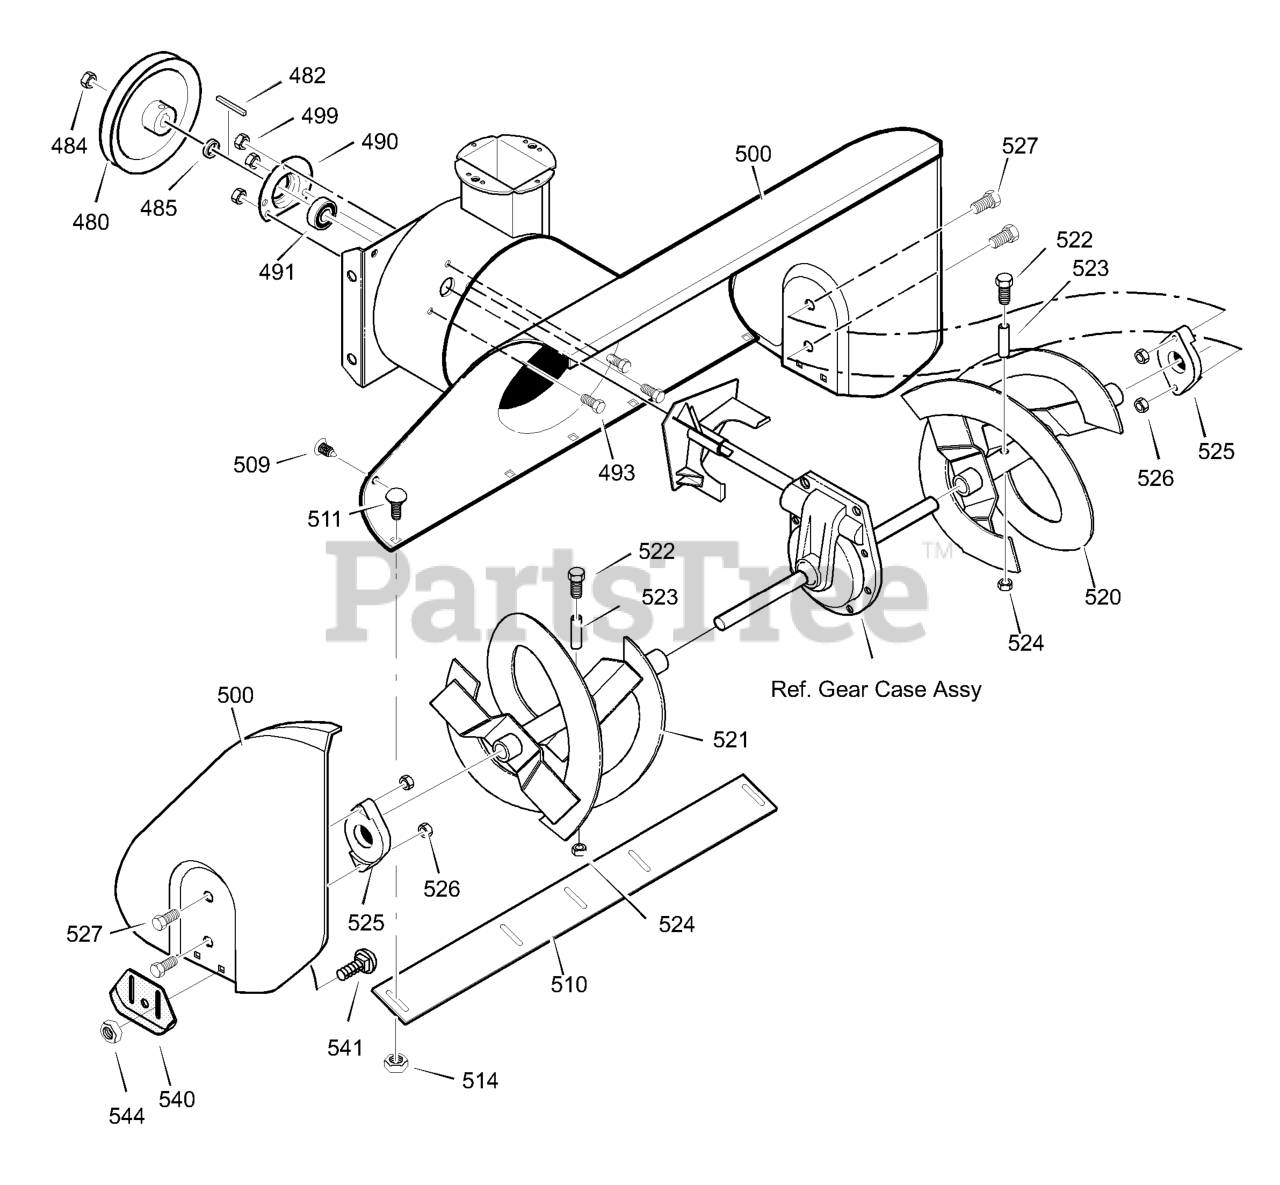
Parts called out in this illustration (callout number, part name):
480	PULLEY, 4L 8.40 OD
482	KEY, SQUARE 3/16 X 3/4
484	NUT, 1/2-20
485	SPACER, FRICTION PULLEY
490	RETAINER, BALL BRNG
491	BEARING, BALL
493	BOLT, HEX 5/16-18X .50
499	NUT, 5/16-18 HEXWDFLLK
500	HOUSING, ASSY
509	PLUG, CHRISTMAS
510	BLADE, SCRAPER
511	BOLT, 5/16-18X.75
514	NUT, 5/16-18
520	AUGER, ASSY, LH
521	AUGER, ASSY, RH
522	SCREW, 1/4-20X1.75
523	SPACER, SLEEVE
524	NUT, 1/4-20
525	BEARING,FLANGE
526	NUT, 5/16-18
527	SCREW, 5/16-18 x 0.75
540	SKID, HEIGHT ADJUST
541	BOLT, 5/16-18 X .75
544	NUT, 5/16-18
